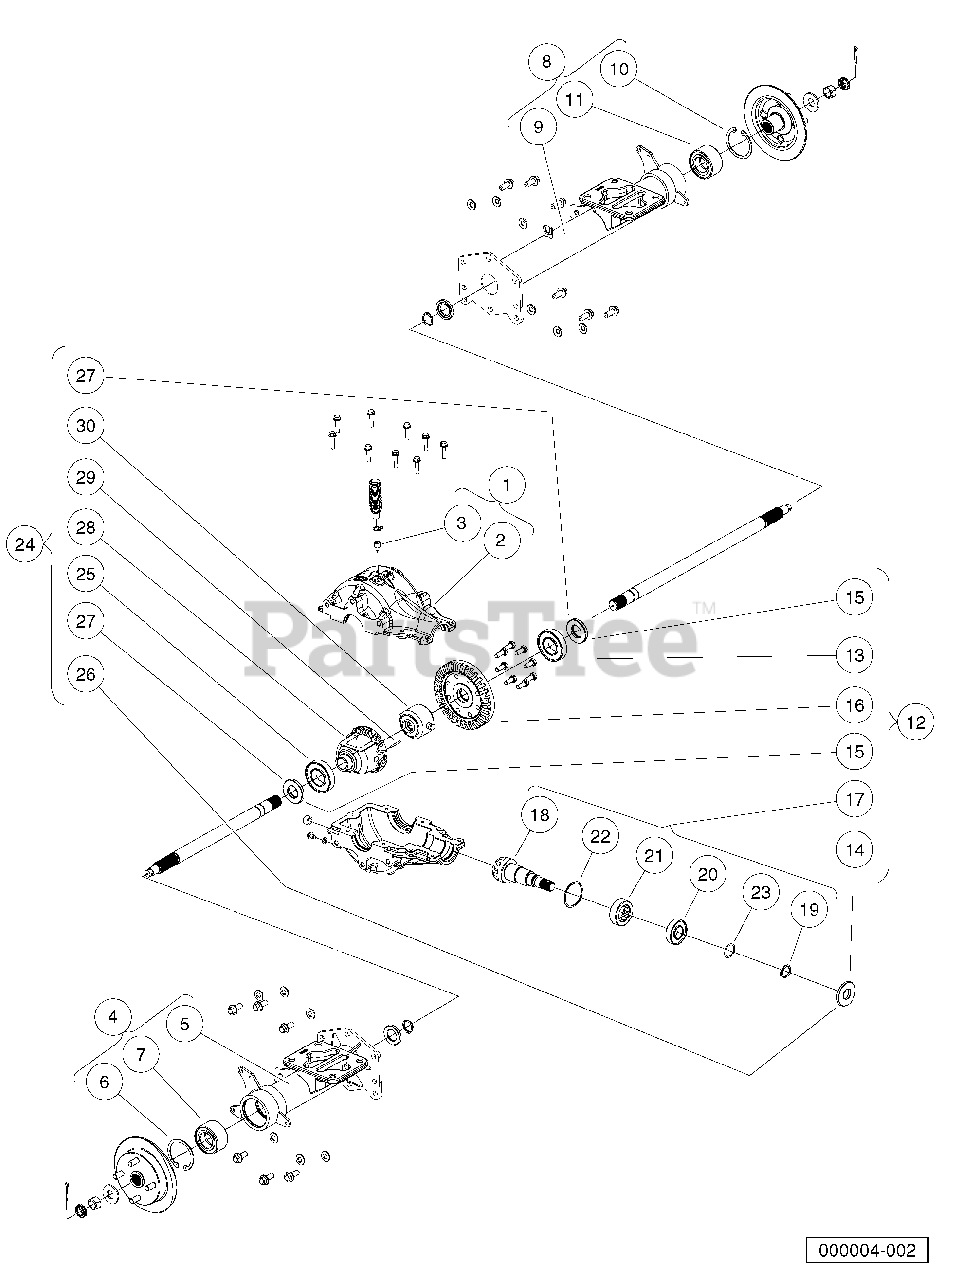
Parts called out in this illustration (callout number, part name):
1	Asm, Gearcase, Upper
2	Gearcase, Upper, Machined
3	Vent, Top, Upper Housing
4	Asm, Axle Tube, RH
5	Weldment, Axle Tube Rh
6	Ring, Retaining, Internal
8	Asm, Axle Tube, LH
9	Weldment, Axle Tube Lh
10	Ring, Retaining, Internal
12	Kit, Rear Axle Gear Repair
13	Bearing, Ball
14	Seal, Dual-Lip 25x 62x 7tc
15	Seal, Dual-Lip 30x 62x 8tc
16	Gear, Ring, 33-Tooth
17	Asm, Pinion W/ Bearings
18	Pinion, I0t Machined
19	Ring, Retaining, External
20	Bearing, Ball
21	Bearing, Needle, Drawn Shell
22	Washer, 2.625 X 2.367 X .06
23	Shim, 1.50 X 1.189 X .008
24	Asm, Differential & Carrier
25	Bearing, Ball
26	Seal, Dual-Lip 25x 62x 7tc
27	Seal, Dual-Lip 30x 62x 8tc
28	Housing, Differential, Mach
29	Pin, Dowel, 4 X 35
30	Asm, Locker, Nongrease/Spacers
